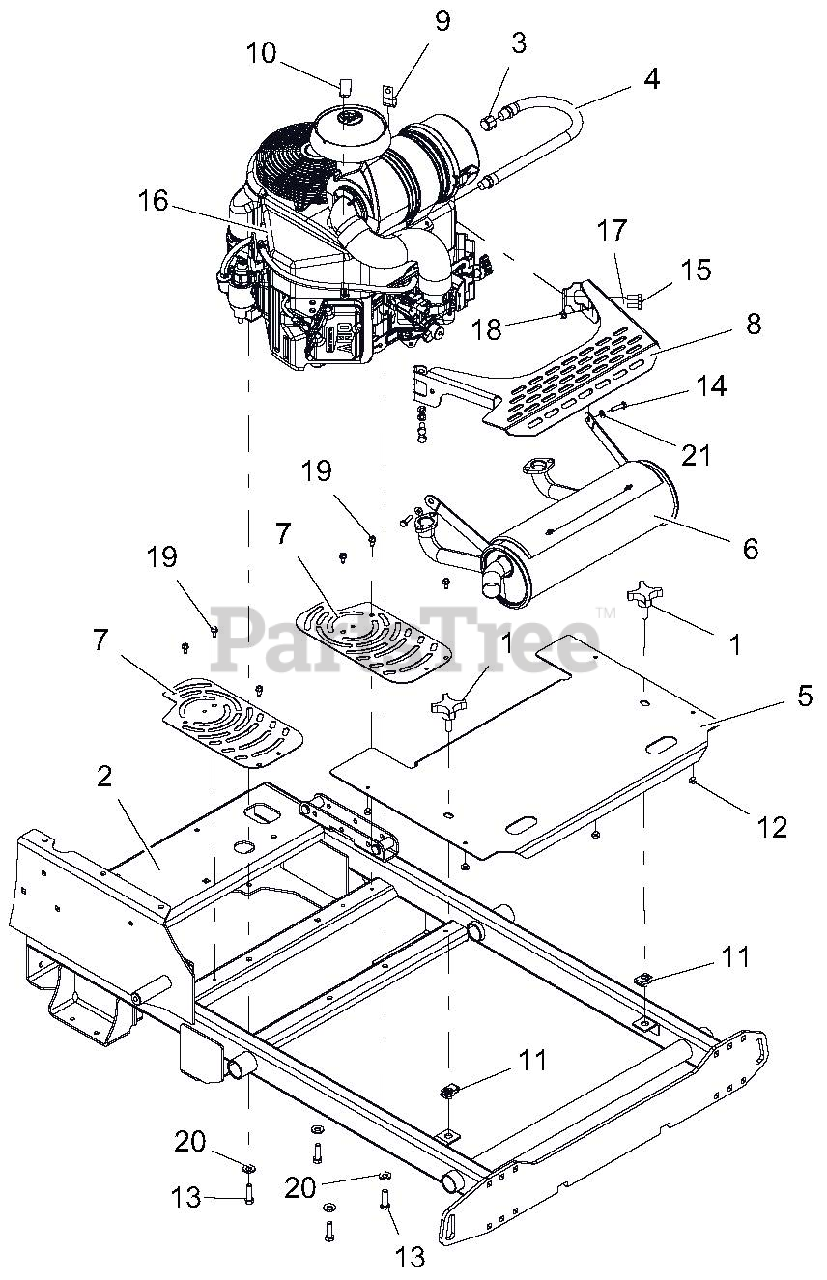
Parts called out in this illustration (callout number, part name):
1	KNOB, 3/8 X 1.25 - 4 PRONG
2	WLDMT, FRAME PROSTANCE
3	PIPE, CAP 3/8 NPT FEMALE
4	DRAIN, M20 OIL
5	SHIELD, FRONT PRO-STANCE
6	EXHAUST, KAWASAKI PROSTANCE
7	GUARD, FAN
8	SHIELD, MUFFLER
10	CLAMP, CUSHIONED STEEL REV
11	NUT, RTNR .375-16X.37
12	BUMPER GROMMET .125 X .25 REV
13	BLT-HEX .38-16X1.25 GR5 YWZC NYTORQ
14	BLT-HEX .25-20X1.00 GR5 YWZC
15	@BLT-HEX M8-1.25X20 YWZC
16	ENGINE, KAWASAKI FX691
17	WSHR-LK .31X.078 REG YWZC
18	NUT-LK-NYL-FLG .25-20 YWZC
19	SCR-TAP .25-20X.50 HWH TR YWZ
20	WSHR, 3/8" SPRING DISC
21	WSHR-FL-STL.281X.62X.065 YWZC
